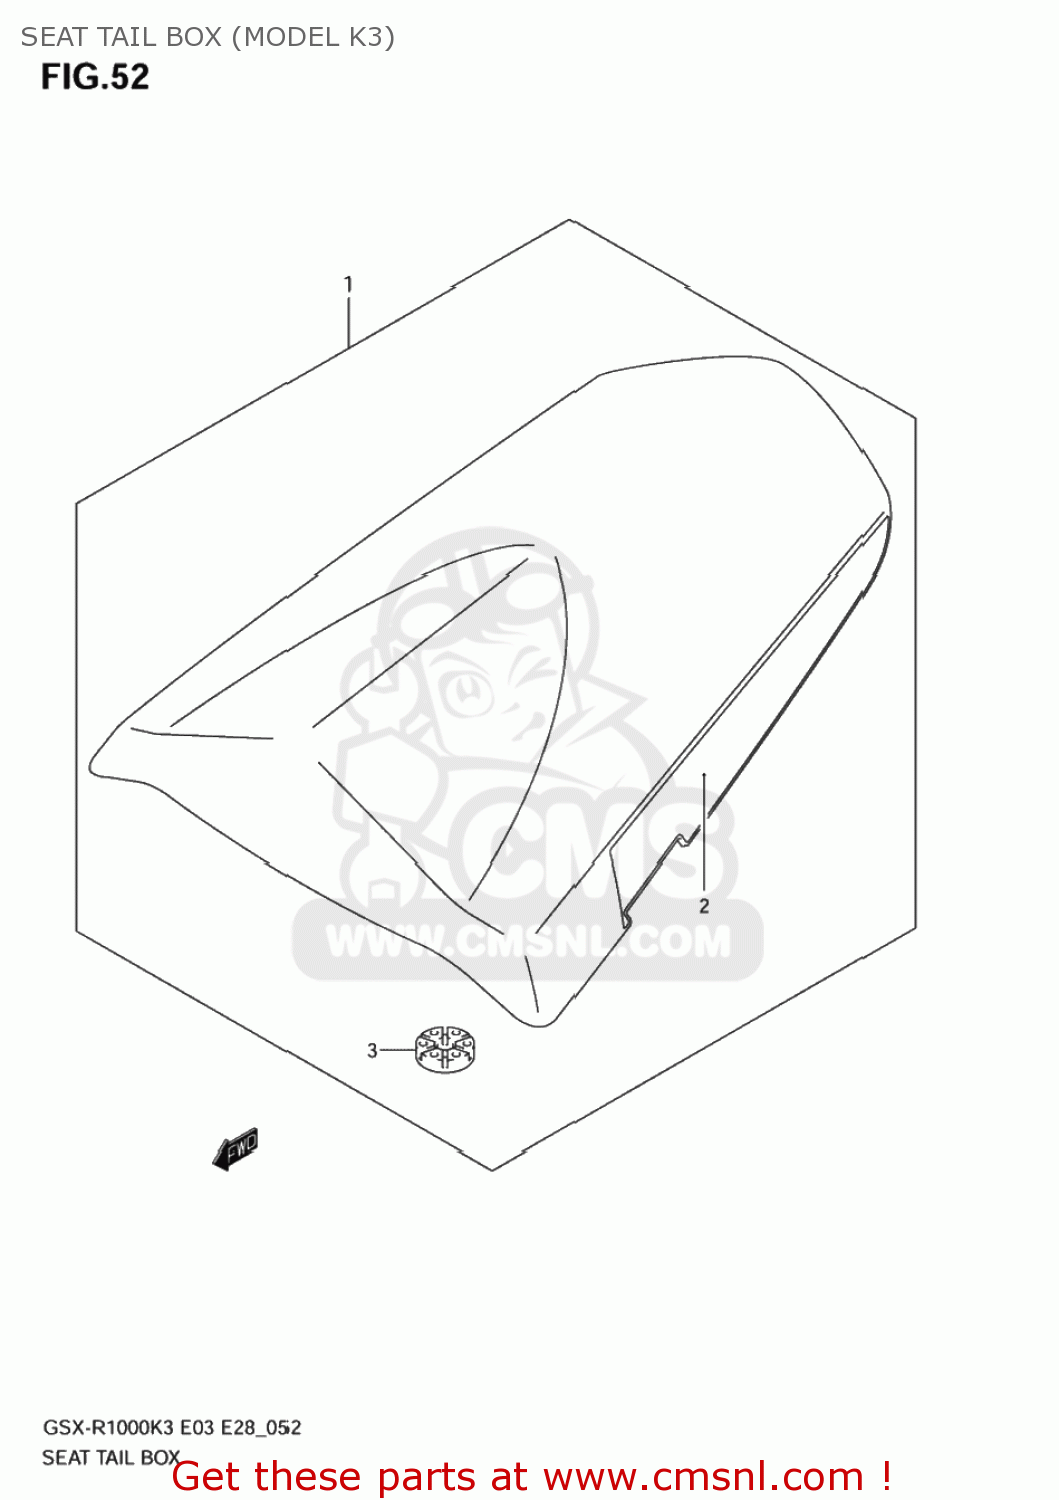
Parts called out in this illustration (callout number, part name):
1	BOX ASSY,SEAT TAIL(WHITE)
2	TAPE SET,BOX SEAT TAIL
3	CUSHION
